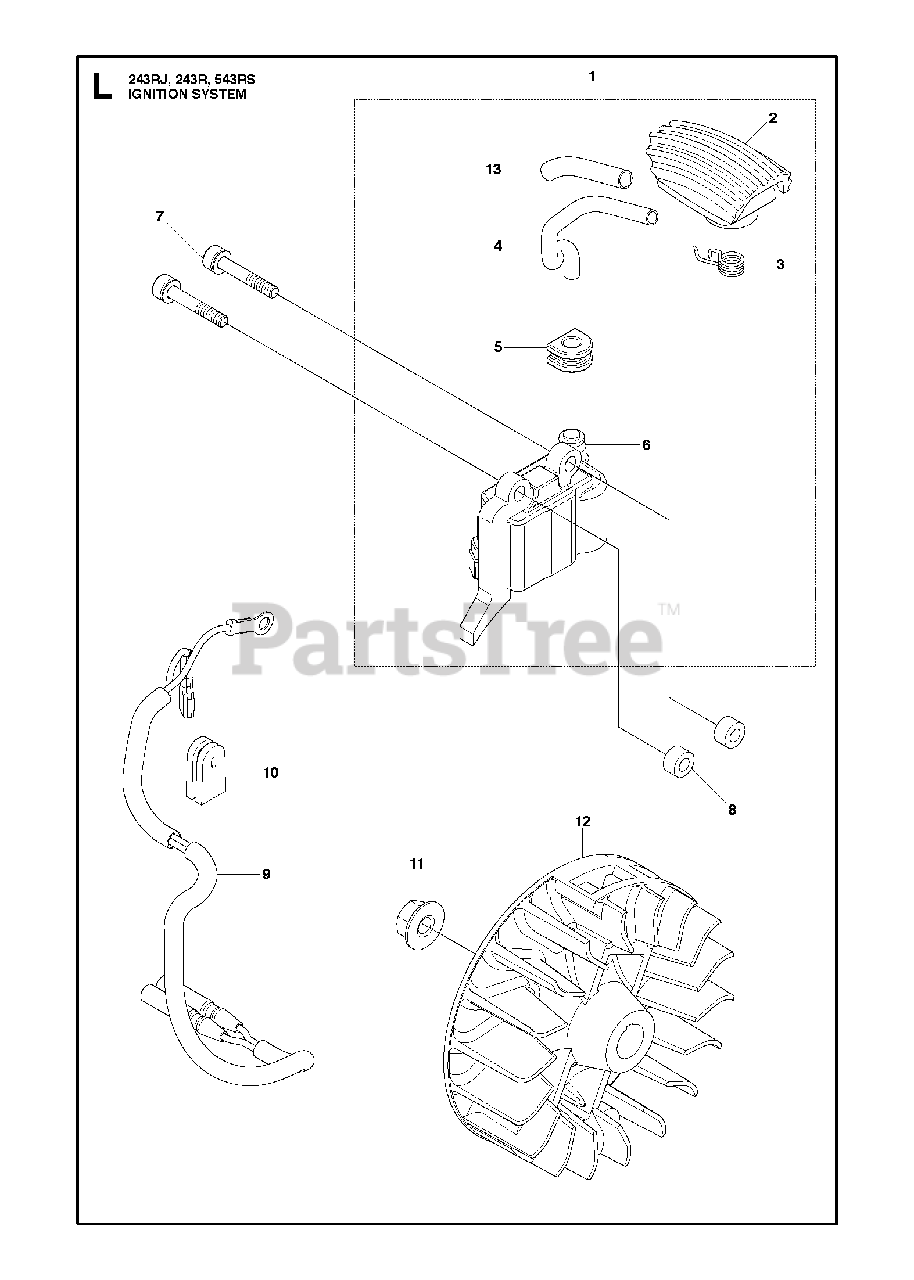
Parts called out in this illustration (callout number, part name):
1	COIL ASSY
1	IGNITION MODULE ASSY
2	CAP
3	SPRING
4	IGNITION MODULE ASSY
4	CORD 848GG071D0
5	Grommet
6	CAP
7	BOLT M4 X 25
8	SPACER
9	CORD-COMP 8488M00150
9	CORD ASSY
11	NUT
12	ROTOR 848GG07111
12	ROTOR
13	TUBE
